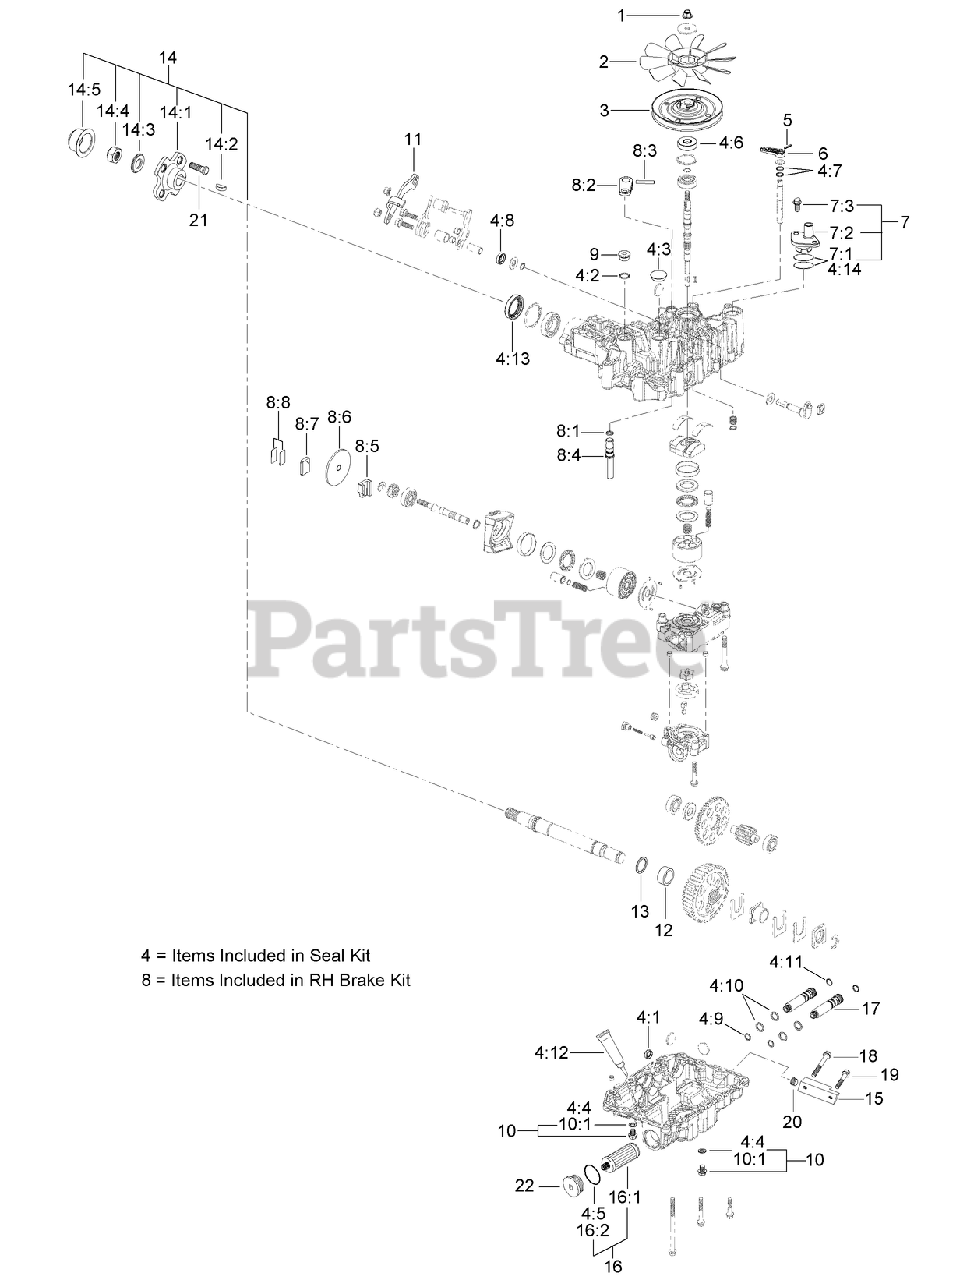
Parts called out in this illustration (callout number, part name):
1	NUT-LOCK
3	PULLEY
4	SEAL KIT
4:1	CAP-SEALING
4:2	O-RING
4:3	CAP-SEAL
4:4	Seal-Washer
4:5	Packing
4:6	SEAL-SHAFT
4:7	Deck ASM
4:8	Deck ASM
4:9	Deck ASM
4:10	Deck ASM
4:11	Deck ASM
4:12	SEALANT
4:13	SEAL-AXLE
4:14	Packing
6	LEVER-BYPASS
7	EXPANSION FITTING KIT
7:1	SEAL-FITTING, EXPANSION
7:2	Fitting
7:3	BOLT-FLANGE
8	RH BRAKE KIT
8:1	Deck ASM
8:2	ARM-BRAKE
8:3	Deck ASM
8:4	SHAFT-BRAKE
8:5	ACTUATOR-BRAKE
8:6	DISC-BRAKE
8:7	SHOE-BRAKE
8:8	SHIM KIT
9	CAP-OIL
10	DRAIN BOLT KIT
10:1	Seal-Washer
11	LEVER-CONTROL, RH
12	SLEEVE
13	WASHER
14	AXLE FLANGE KIT
14:1	Deck ASM
14:2	Key-Woodruff
14:3	Deck ASM
14:4	NUT-LOCK
14:5	NUT-CAP
15	MANIFOLD
16	HYDRO FILTER KIT
16:1	FILTER
16:2	O-RING
17	CONNECTOR
19	SCREW-HHF
21	STUD-WHEEL
22	CAP-OIL FILTER
